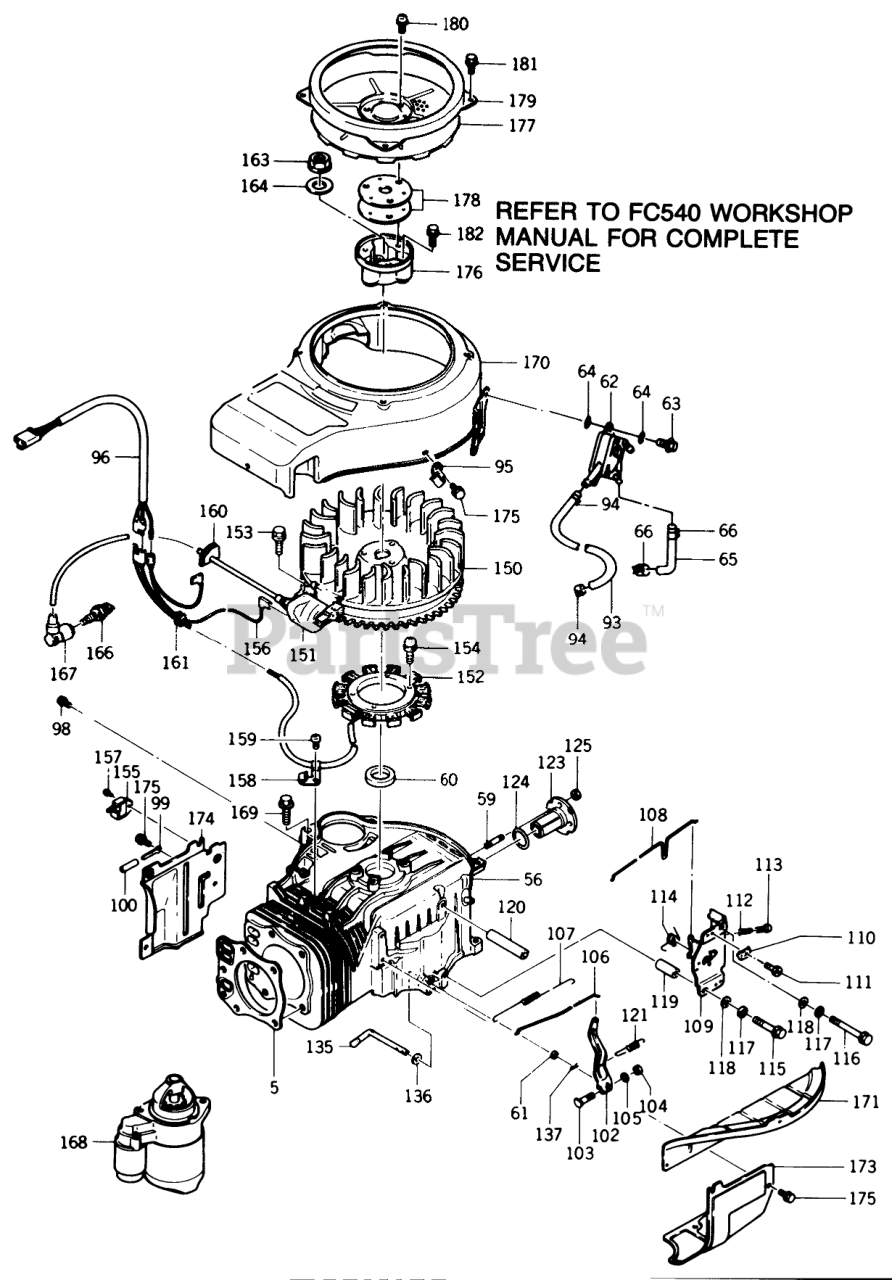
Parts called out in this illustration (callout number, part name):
5	GASKET HEAD
56	CASE-CRANK
60	SEAL OIL
61	SEAL-OIL, VC (6X10X2.5)
62	PUMP-FUEL ASSY
63	Bolt
64	WASHER
95	CLAMP
96	HARNESS
98	BOLT-FLANGED
99	CLAMP
102	ARM ASS'Y
103	Bolt
104	NUT 6MM
105	Washer
106	LINK GOVERNOR
107	SPRING-LINK
108	LINK CHOKE
109	PANEL-CONTROL
110	CLAMP
112	SPRING
113	SCREW PAN HEAD 4X25
114	SPRING
115	BOLT (6 X 50)
116	BOLT (6 X 90)
117	HANDLE-RECOIL
118	WASHER, CLUTCH
119	COLLAR
120	COLLAR
121	SPRING
123	SHAFT
124	O-RING
125	Nut
135	ARM-PIVOT
136	WASHER-PLAIN 6MM
137	Pin
150	FLYWHEEL ASS'Y
151	COIL IGNITION
152	COIL-CHARGING
154	SCREW (6 X 25)
155	IGNITER
156	LEAD WIRE
157	SCREW (4 X 8)
158	CLAMP
159	SCREW
160	GROMMET
161	GROMMET
164	WASHER
166	SPARK PLUG
167	CAP-SPARKPLUG
168	Starter Assembly See Section 10-7 For Complete Parts Breakdown
169	BOLT (8 X 35)
170	HOUSING-FAN
171	HOUSING-FAN
173	SHROUD
174	SHROUD
175	Bolt 6 x 12
176	BRACKET
177	SCREEN
179	GUARD
180	CLAMP
181	Bolt
182	BOLT (8 X 20)
